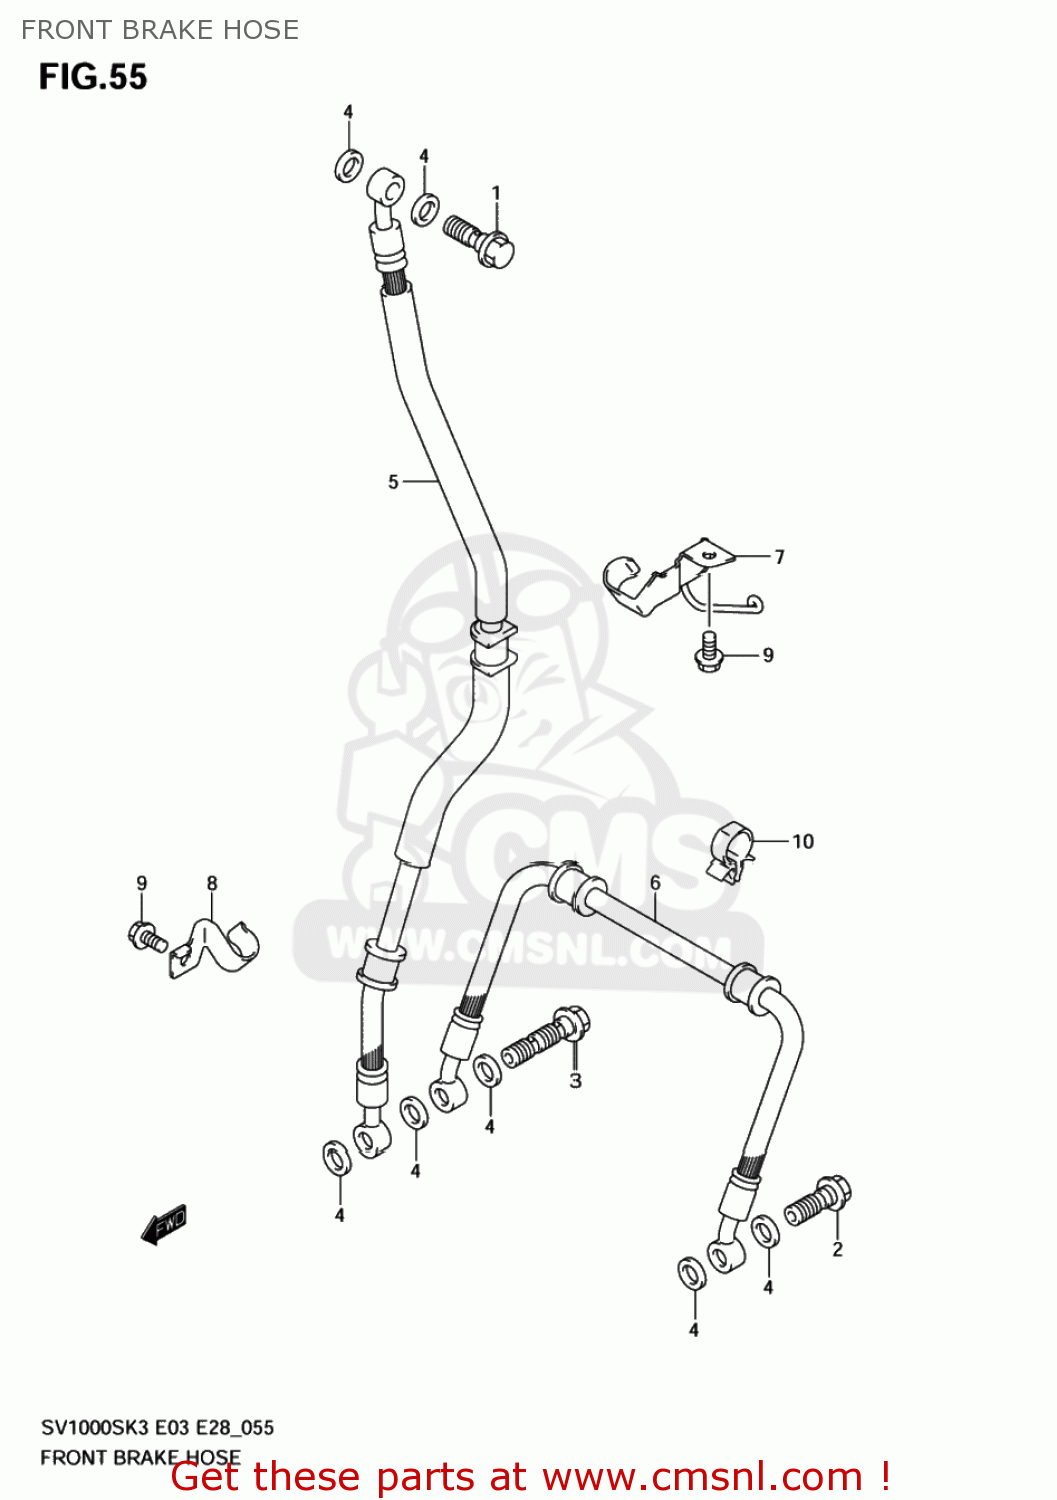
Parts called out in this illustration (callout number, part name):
1	BOLT UNION
2	BOLT UNION
3	BOLT UNION
4	WASHER(10X15X1.5)
5	HOSE,FR BRAKE NO.1
6	HOSE,FR BRAKE NO.2
7	CLAMP,FR BRAKE HOSE
8	CLAMP,FR BRAKE HOSE NO.2
9	BOLT
10	CLAMP
